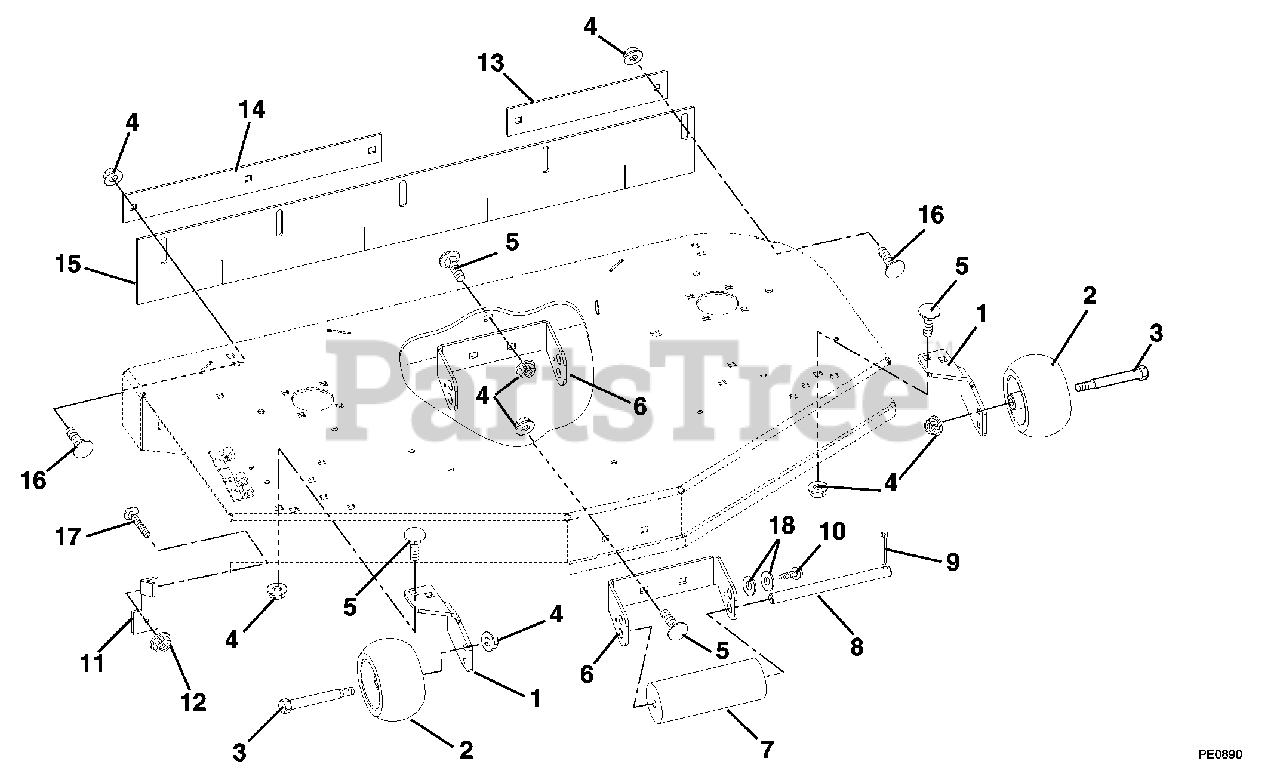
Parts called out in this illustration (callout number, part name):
1	Bracket, Anti Scalp
2	Wheel 5 x 3
3	Bolt, Shoulder .38-16 x 2.50 Hex Washer Head Grade 5
4	Nut, Locking Top Flange .38-16
5	Bolt, Round Head Square Neck .38-16 x .75 Grade 5
6	Bracket, Roller Mount
7	Roller
8	Pin, Retainer
9	Pin, Cotter .25 x 1.00
10	Screw, Tapping .25-20 x .50 Hex Washer Head
11	Bracket, Chute Lock
12	Nut, Spin Lock Flange .375-16
13	Bar, Left Hand Retainer Striper
14	Bar, Retaining Striper (034)
14	Bar, Retaining Striper (036)
14	Bar, Retaining Striper (038, 040)
15	Striper, Rubber-40" (034)
15	Striper, Rubber-44" (036)
15	Striper, Rubber-48" (038)
15	Striper, Rubber-52" (040)
16	Bolt, Round Head Square Neck .38-16 x 1.00 Grade 5
17	Bolt, Round Head Square Neck .38-16 x 1.25
18	Washer, Flat Steel .344 x .688 x .065
